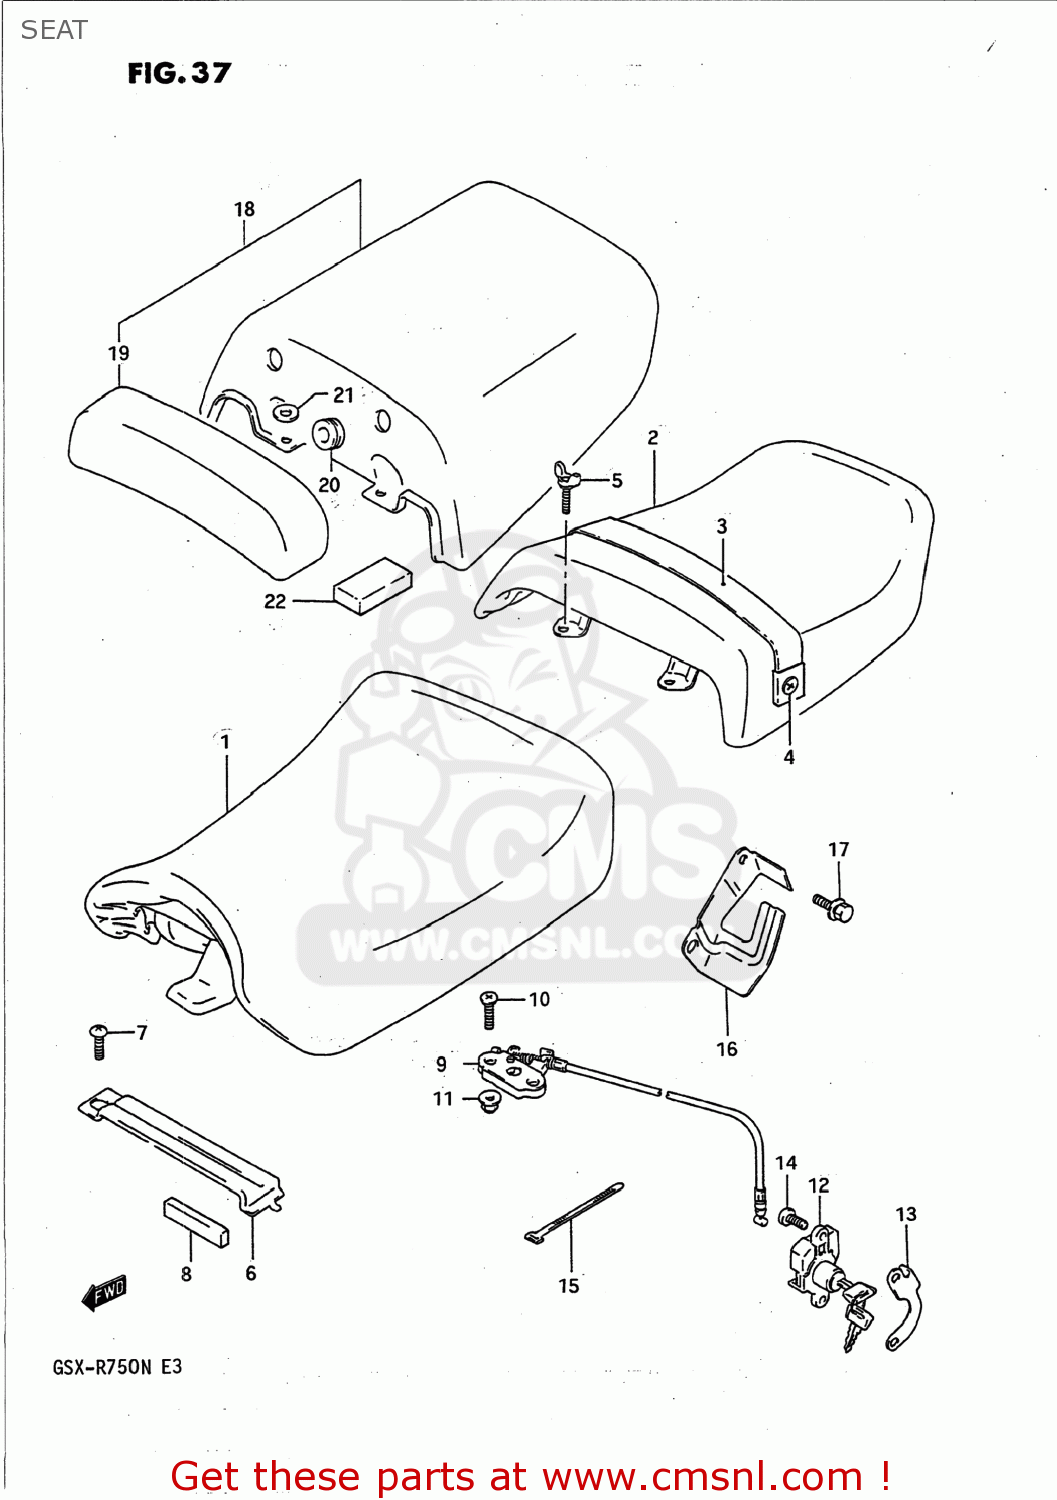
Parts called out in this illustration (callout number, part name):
1	SEAT ASSY
2	SEAT ASSEMBLY,PILLION
3	BAND COMP,SEAT
4	BOLT
5	SCREW(6X20)
6	PLATE,SEAT SUPPORT RR
7	SCREW
8	CUSHION,PLATE SEAT SUPPORT
9	BRACKET,SEAT SUPPORT RR
10	SCREW
11	NUT
12	LOCK SET,SEAT
13	PLATE,SEAT LOCK
14	SCREW(6X12)
15	CLAMP
16	PLATE,SEAT LOCK CABLE
17	BOLT
18	COVER SET,SINGLE SEAT
19	BACKREST,SEAT(BLACK)
20	CUSHION
21	WASHER
22	MUD GUARD,REAR FENDER
